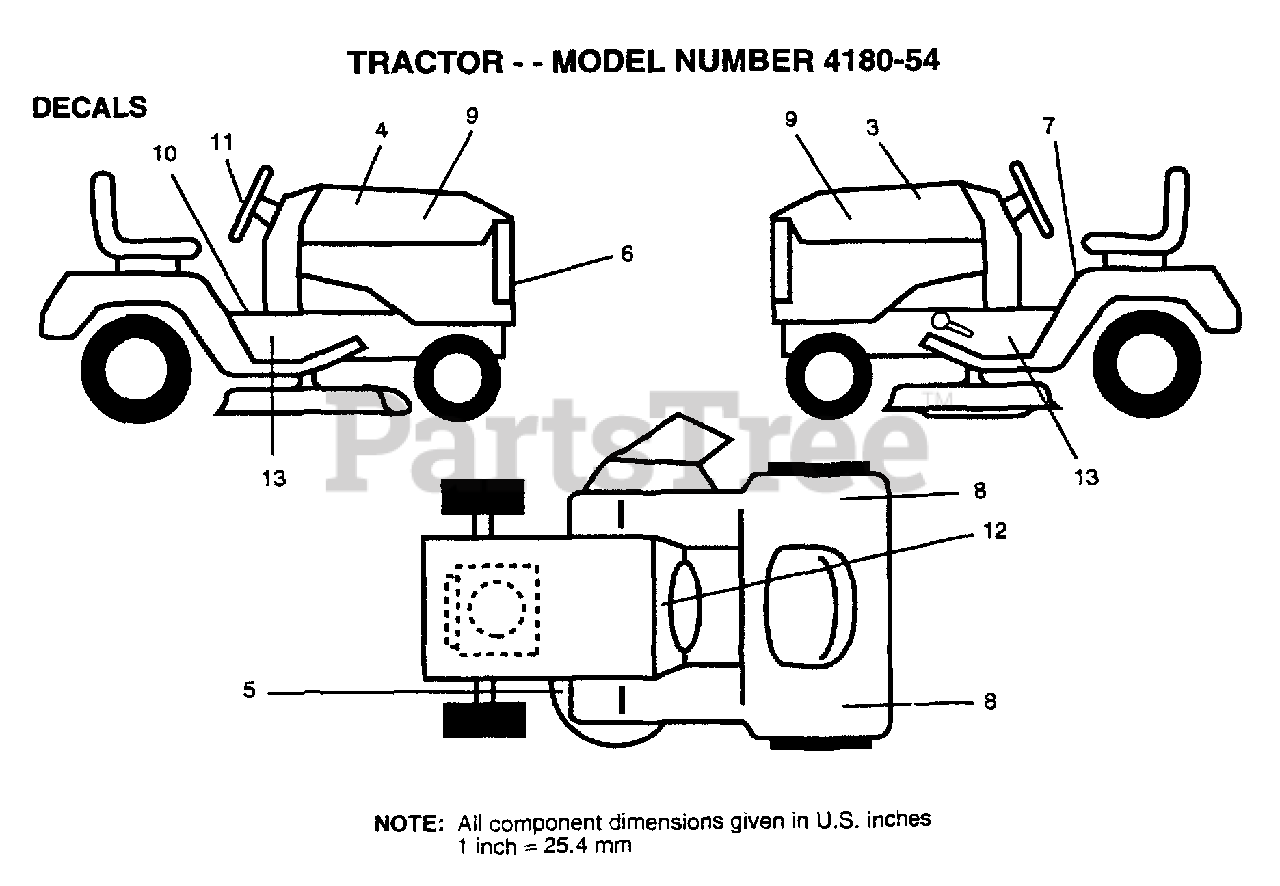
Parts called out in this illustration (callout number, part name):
2	"DECAL,HP ENGINE"
3	HOOD DECAL LH
5	"DECAL.V.BELT.44"""
6	GRILL DECAL
7	DECAL
8	REFLECTOR-TAIL YT
9	NAMEPLATE LOGO
10	DECAL BRAK PARK
12	DECAL.DASH.INST.
